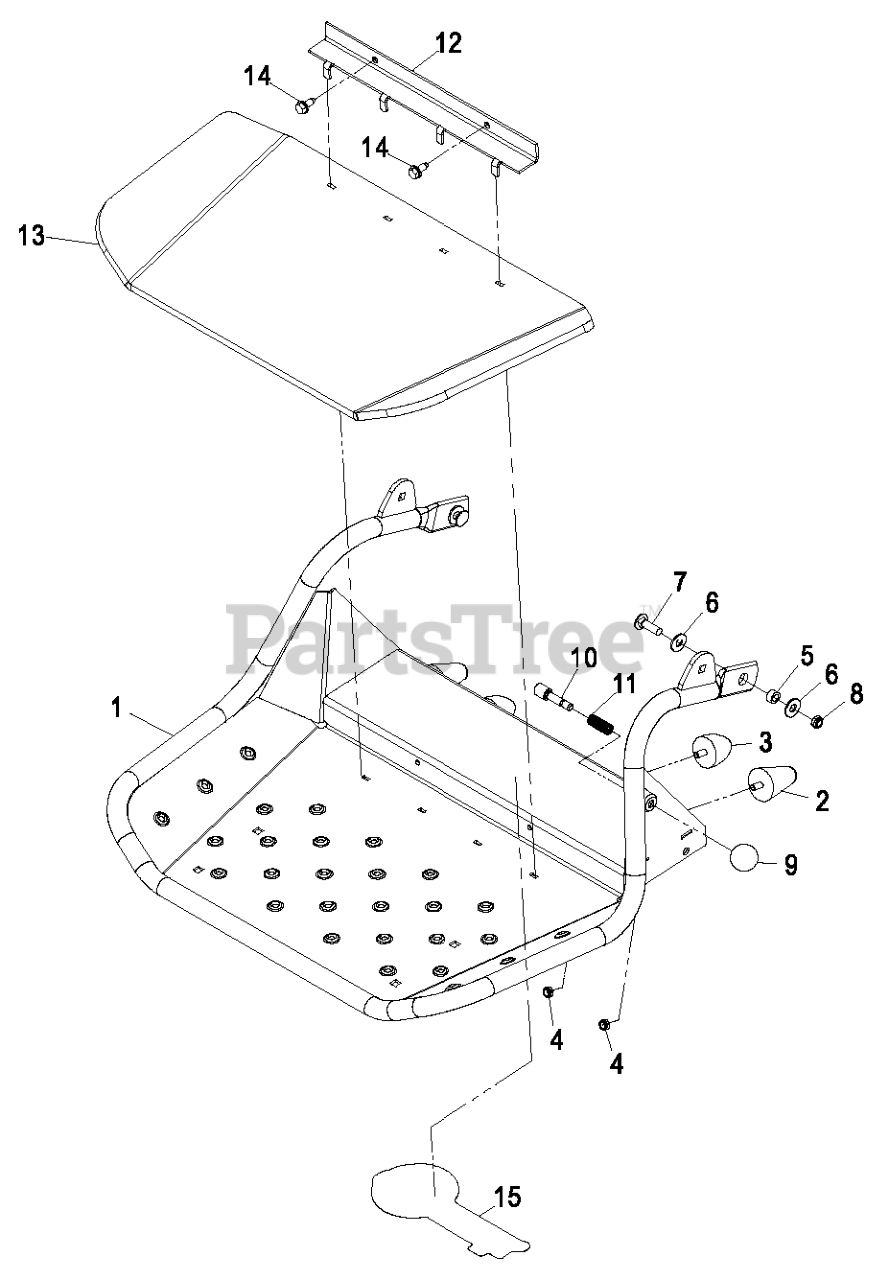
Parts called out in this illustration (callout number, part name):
1	PLATFORM ASM
2	BUMPER-RUBBER
3	BUMPER-RUBBER
4	NUT-LOCK, NI
5	SPACER
6	WASHER-FLAT
7	BOLT-CARR
9	KNOB-BALL
12	CLAMP-SHIELD
14	Screw-HWH 5/16-18 X 3/4 Tf
15	DECAL, EXMARK LOGO
